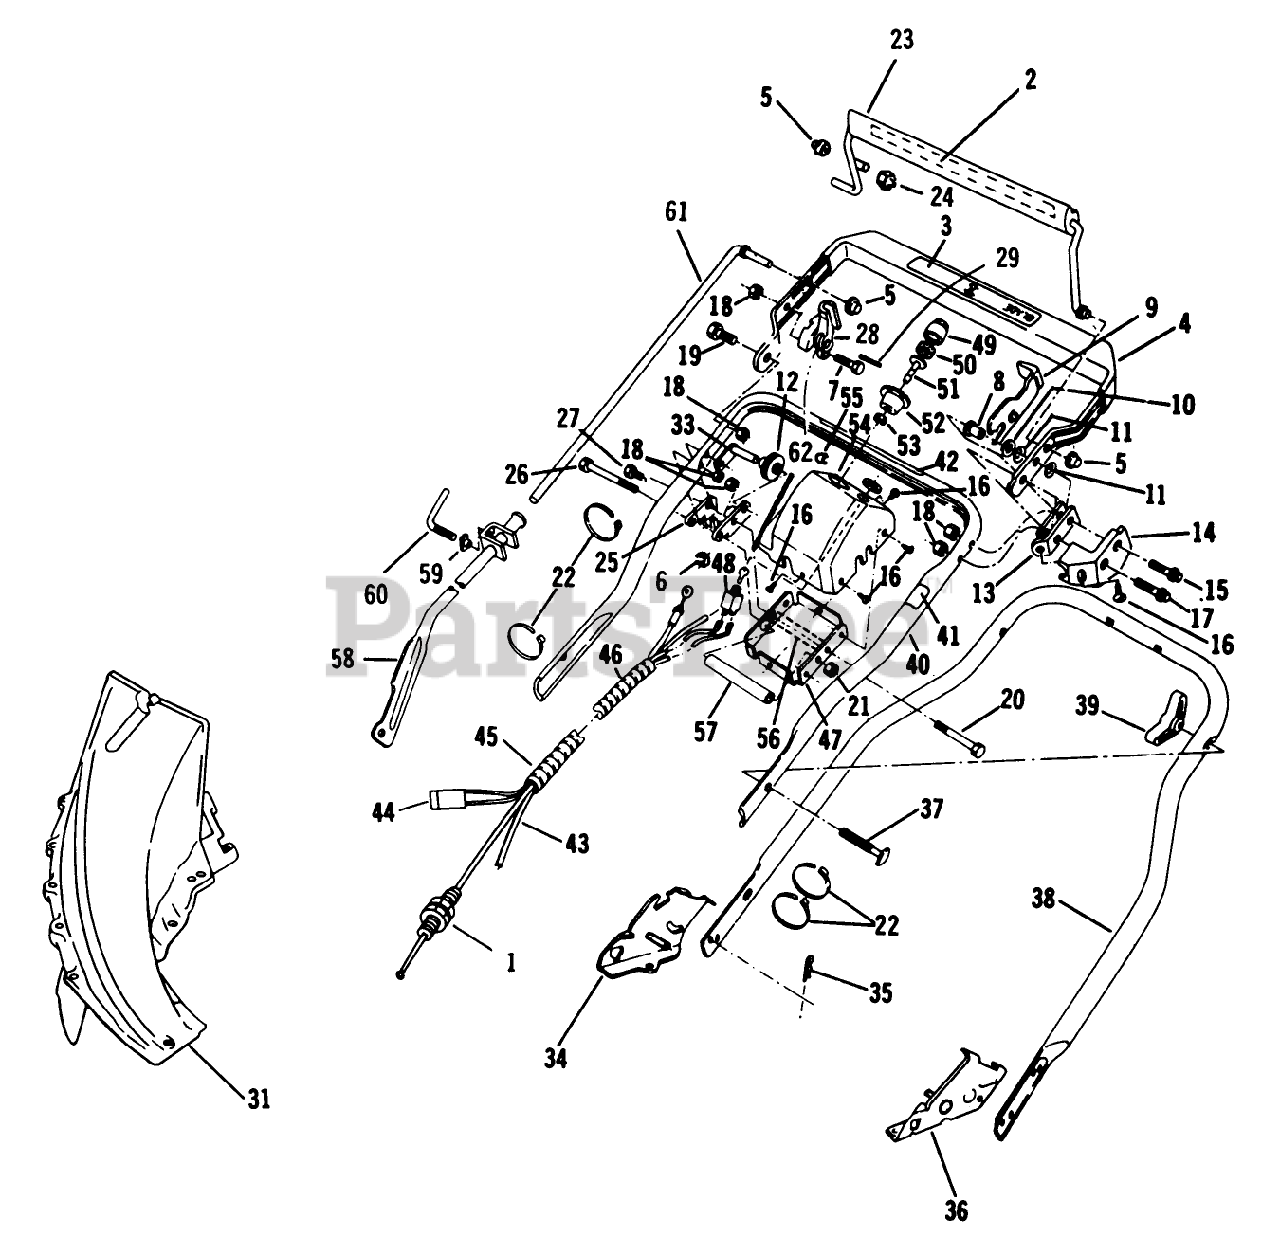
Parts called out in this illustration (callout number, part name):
1	CONTROL CABLE
6	RET. RING
8	SPACER
10	WASHER M
13	DOWN STOP
14	LOCKOUT GUARD
15	BOLT SHOU
16	SCREW F
17	SCREW
18	LOCKNUT E
19	BOLT
24	NUT ACORN
26	BOLT-CONSOLE
32	HANGER AY
34	BRACKET ASM - HANDLE, SP, RH
35	HAIR PIN
36	BRACKET ASM - HANDLE, SP, LH
37	BOLT QUALITY
39	NUT-WING
50	FILTER S
53	LOCKNUT S
56	SPACER
61	CONTROL ROD
